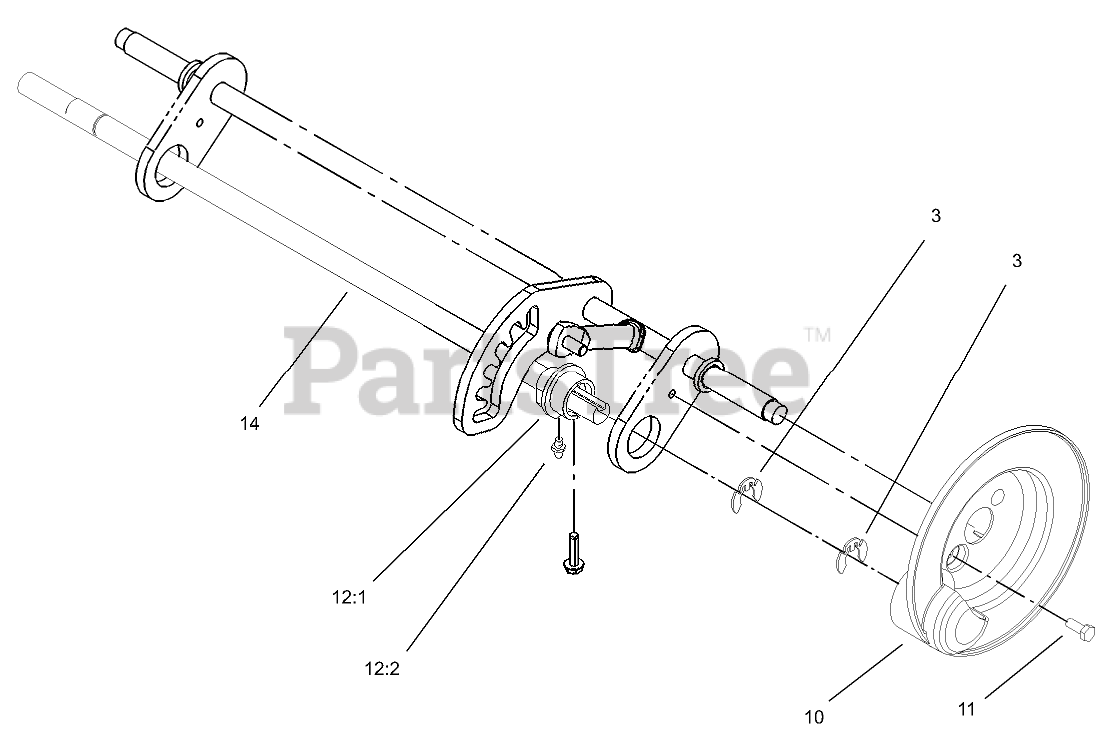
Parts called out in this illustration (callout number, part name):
3	RING-CLIP, LOCKING
10	COVER-GEAR
11	SCREW-TAPTITE
12	BUSHING ASM
12:1	BUSHING
12:2	FITTING-GREASE
14	SHAFT-PIVOT
